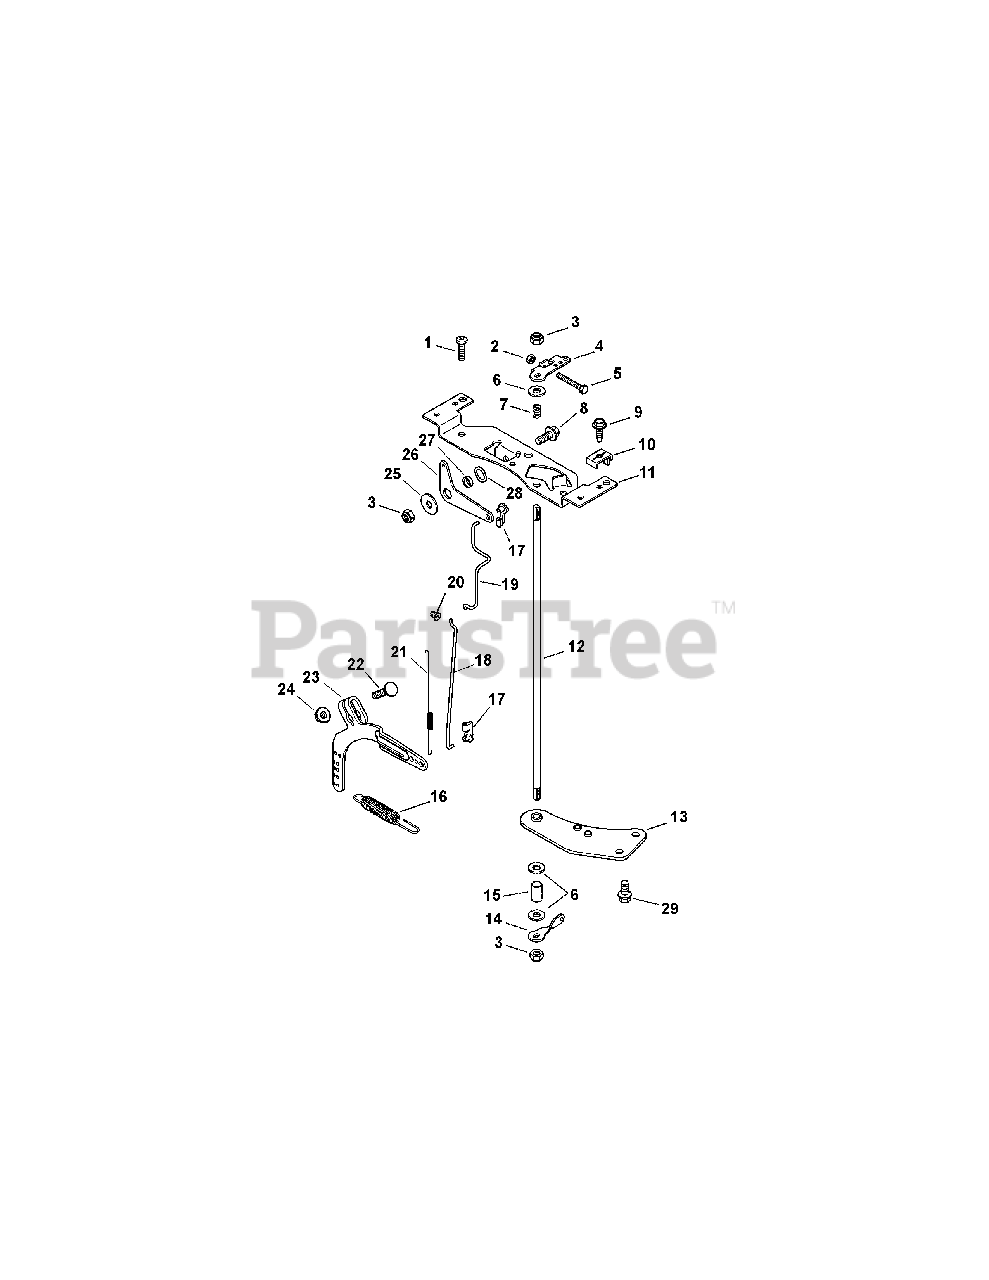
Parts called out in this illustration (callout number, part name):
1	SCREW, PHL HD 11-16X3/4''
3	NUT, LOCK M6X1.0
4	LEVER, THROTTLE CONTROL
5	SCREW, CAP M4X.7X30
6	WASHER, FLAT 1/4''
7	SPRING, THROTTLE SHAFT
8	SCREW, FLG M6X1.0X16
9	SCREW, FLG THD FRM M5X0.8X16
10	CLAMP, CABLE
11	BRACKE! T, CONTROL
12	SHAFT, THROTTLE
13	BRACKET, THROTTLE SHAFT
14	LEVER, THROTTLE CONTROL
16	SPRING, GOVERNOR (GREEN)
17	BUSHING, THROTTLE LINKAGE
18	LINKAGE, THROTTLE
19	LINKAGE, CHOKE
20	BUSHING, LINKAGE ! RETAINING
21	SPRING, LINKAGE
22	BOLT, RD HD SQ NECK M6X1.0X25
23	LEVER, GOVERNOR
24	NUT, FLG M6X1.0
25	WASHER, FLAT 1/4''
26	LEVER, CHOKE
28	WASHER, SPRING 3/8''
29	SCREW, FLG THD FRM M6X1.0X16
